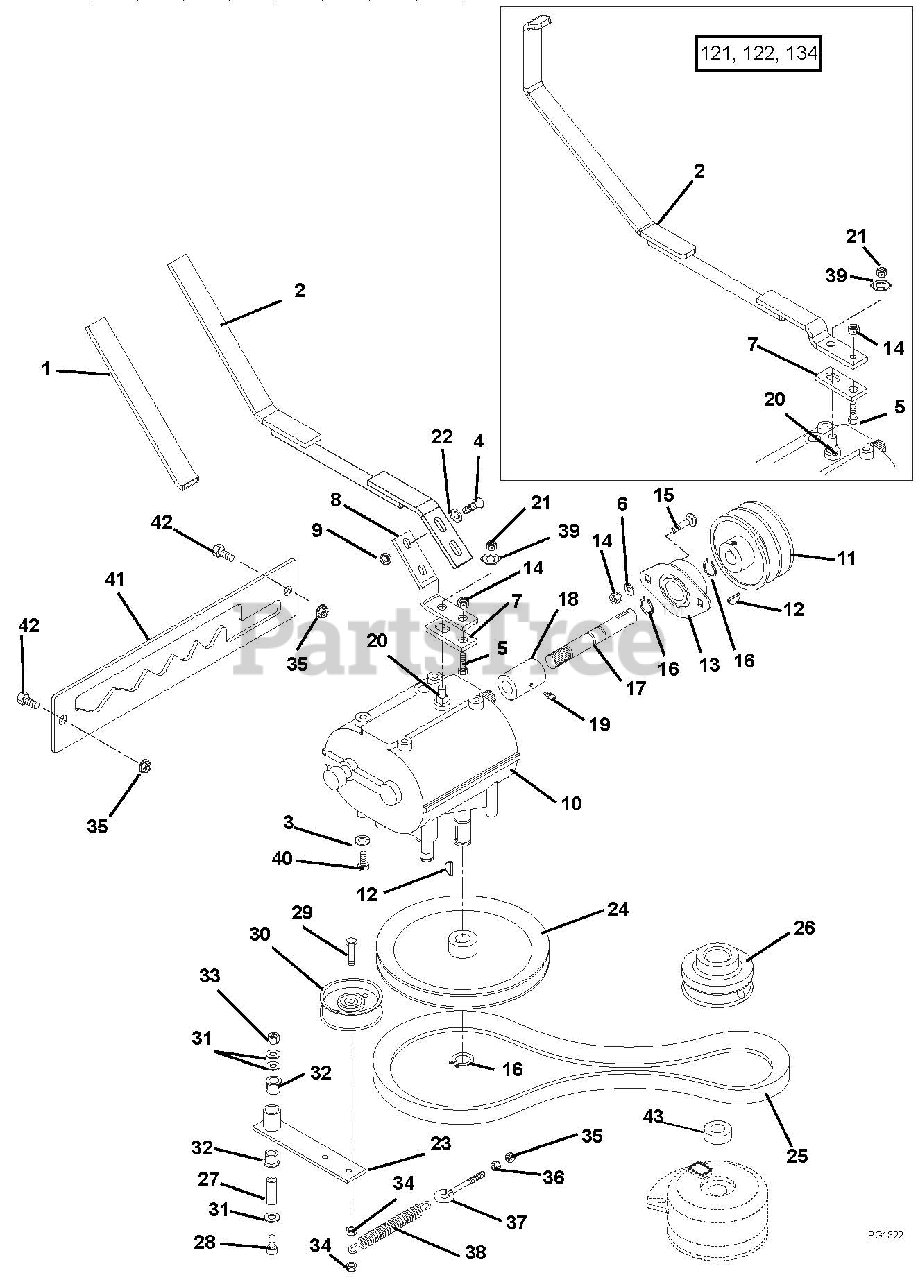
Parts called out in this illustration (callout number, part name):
1	Grip
2	Lever, Shift
3	Washer, Locking .31 x .078 Regular
4	Bolt, Hex .31-18 x 1.00 Grade 5
5	Bolt, Hex .25-20 x 1.00 Grade 5
6	Washer, Flat-Steel .25 x .562 x .049
7	Plate, Shift
8	Arm, Shift
9	Nut, Locking-Top-Flange .31-18
10	Transmission
11	Sheave, Drive
12	Key, Woodruff .19 x .75
13	Bearing, Flange .625 x 1.875 x .797
14	Nut, Locking-Nylon .25-20
15	Bolt, Round Head Square Neck .25-20 x .75 Grade 5
16	Ring, Retaining-External .579 x .930
17	Shaft, Half
19	Fitting, Lube, .25-28
20	Switch, Neutral Start N.O.
21	Nut, Locking-Center .38-24
22	Washer, Flat-Steel .344 x .688 x .065
23	Weldment, Ground Drive Idler
24	Pulley, V 7.50 x .63 Sheave Transmission
24	Pulley, V 7.50 x .626
25	V-Belt 4L-Section 33.9
26	Sheave, Clutch
27	Bushing, Steel .56 x .745 x 2.04
28	Bolt, Hex .50-13 x 3.25 Grade 5
29	Bolt, Hex .38-16 x 2.00 Grade 5
30	Idler-Pulley Flat 3.25 x .625
31	Washer, Flat-Steel .531 x 1.06 x .095
32	Bushing, Flange Nylon .762 x 1.00 x .58 x 1.48
33	Nut, Locking-Nylon .50-13
34	Nut, Locking-Jam-Center .375-16
35	Nut, Locking-Nylon .38-16
36	Nut, Hex .38-16
37	Eye Bolt
38	Spring, Extension
39	Washer, Locking .38 x .13
40	Bolt, Hex .31-18 x .75 Grade 5
41	Plate, Shift Lever Detent
42	Bolt, Hex .38-10 x 1.00 Grade 5
43	Bushing, Spacer 1.032 x 1.25 x .25 Promaster
